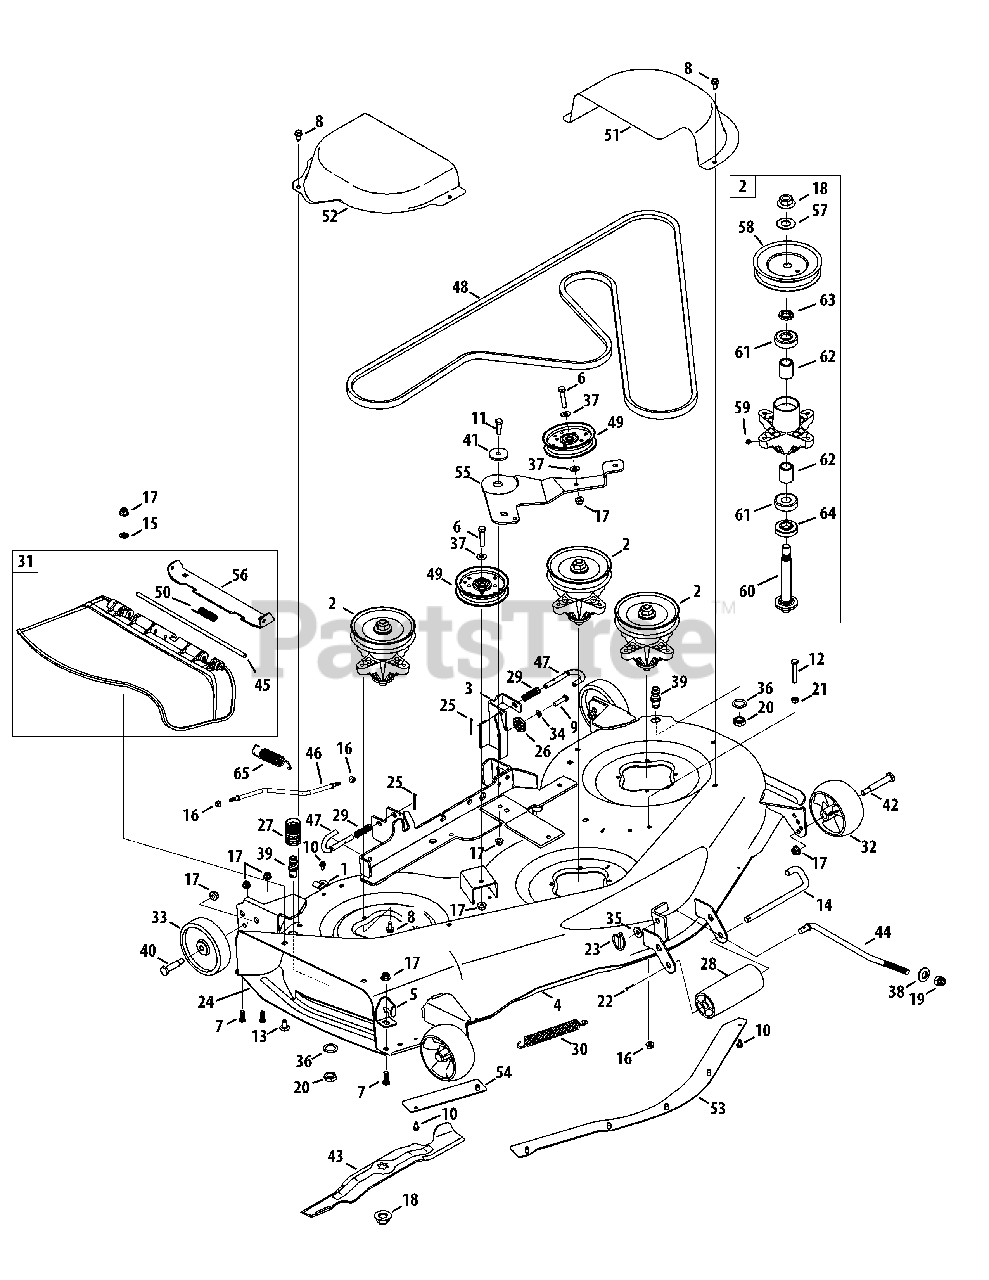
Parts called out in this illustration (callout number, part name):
1	Bracket, Hook, Retainer
2	Spindle Assembly, Pulley, 5.39 Dia.
3	Bracket Assembly, Deck, Hanger LH
4	Deck Assembly, 50"
5	Stop, Chute, Deflector
6	Hex Screw, 3/8-16, 1.75, Gr5
7	Hex Screw, 3/8-16, 1.00, Gr5, Spec
8	Screw, Self-tapping, 5/16-18, .750,
9	Hex Screw, 5/16-18, 1.25, Gr5, Std
10	Screw, Self-tapping, 1/4-20, 0.500
11	Hex Screw, 3/8-16, 1.25
12	Hex Screw, 5/16-18, 2.00, Gr5, Std
13	Bolt, Carriage, 3/8-16, 0.75, Gr1
14	Roller Pin-1/2 Dia. x 7.31
15	Nut, Push, 3/8
16	Nut, Flange Lock, 5/16-18, Nylon
17	Nut, Flange Lock, 3/8-16, Nylon
18	Nut, Flange, 5/8-18
19	Nut, 1/2-13
20	Nut, Hex, M16-1.5
21	Nut, Hex, 5/16-18, Gr5
22	Pin, Cotter, 3/32, 1.0
23	Pin, Lynch, .1875
24	Finger Guard
25	Pin, Cotter, 1/8 x 1.25
26	Gear, Deck, Adjustment
27	Coupler, Water
28	Roller, Front
29	Spring, Compr’, .535 OD x 1.751
30	Spring, Extension, .94 OD x 6.74
31	Chute Assembly
32	Wheel, Deck, 5.0 Dia. Ball
33	Wheel, Deck 5.0 x 1.38
34	Washer, Lock, 5/16, Regular Duty
35	Washer, Flat, .531 x 1.25 x .100
36	Washer, Lock, 5/8, Int Tooth
37	Washer, Flat, .406 x .875 x .059
38	Washer, Bell, .63 x 1.25 x .18
39	Port, Water
40	Bolt, Shoulder, .496 x 1.525, 3/8-16
41	Spacer, Shoulder, .8840 x .190
42	Bolt, Shoulder, .496 x 2.50, 3/8-16
43	Blade, 17.90 Star 2 In 1
44	Rod, Lift, Deck, Front, 11.7
45	Pin, Hinge, .3175 Dia. x 14.06 ,1
47	Rod, Deck Release
48	Belt, V-Type
49	Pulley, Idler, 4.25"Dia.
50	Spring, Torsion, .44 I.D. x 2.0,
51	Cover, Belt, LH 50"
52	Cover, Belt, RH 50"
53	Skirt, Center, 50"
54	Skirt, RH, 50"
55	Bracket, Idler, 50" w/o Spacer
56	Bracket, Chute 50/54"
57	Washer, Flat, .760 X 1.50 X .120
58	Pulley, Deck, 5.39 Dia.
59	Lube Fitting, 3/16
60	Shaft, Spindle, 5.75 Lg.
61	Bearing, Ball, .787id x 1.85 Od x .551
62	Spacer, .80 x 1.10 x 1.322
63	Spacer, .790 x 1.25 x .175
64	Spacer, .79 x 1.82 x .55lg.
65	Spring, Extension, 1.15 OD x 5.99
